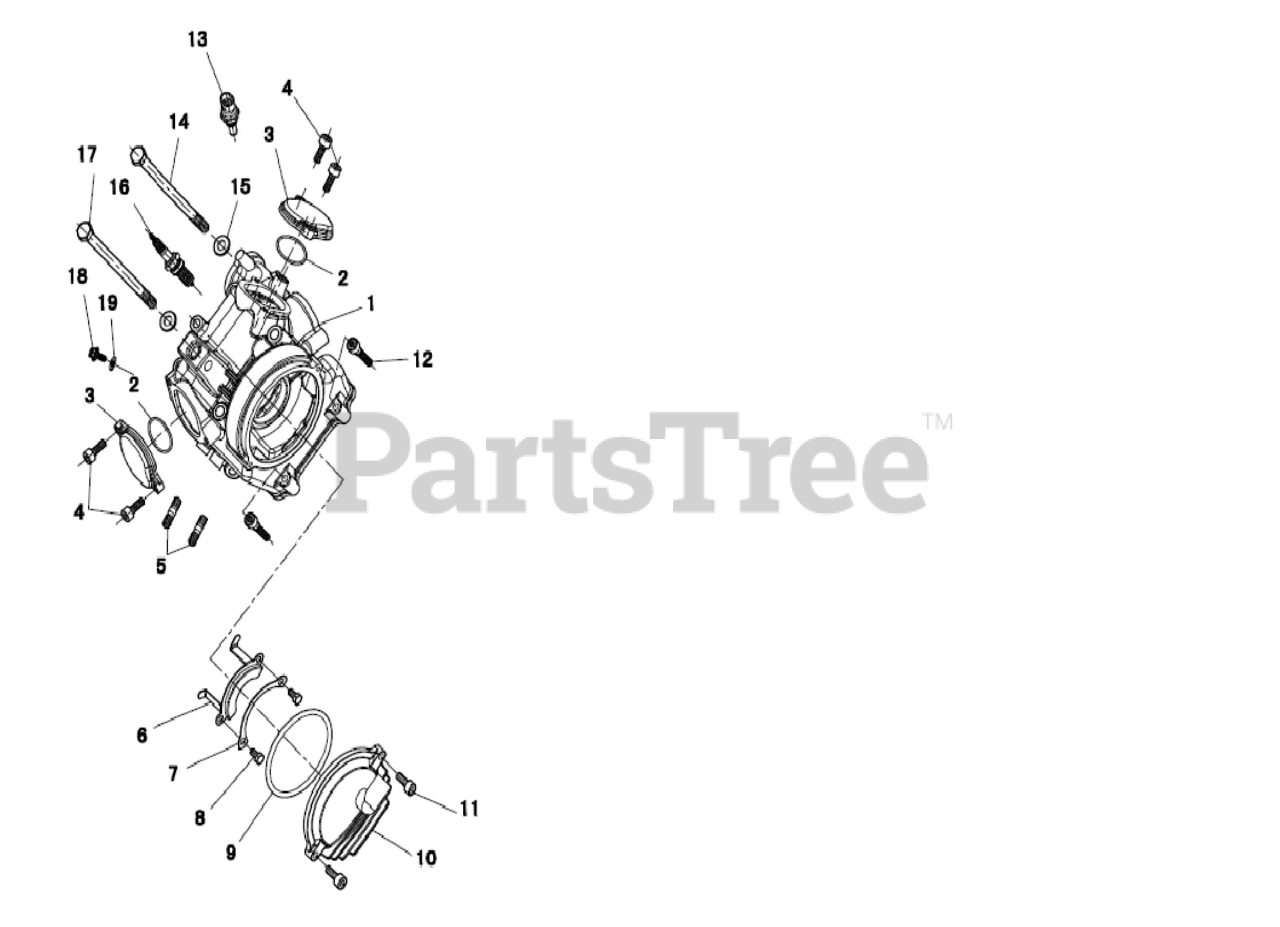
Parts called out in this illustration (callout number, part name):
1	CYLINDER HEAD ASSEMBLY
2	O-RING 58 X 2.4
3	VALVE COVER
4	Hex head cap screw M6X20
5	Stud M8X45(SUS)
6	CAM BEARING HOLDER
7	BOLTS SPACING PLATE
8	BOLTS HEXAGON HEAD M6 X 16
9	O-RING 107 X 2.4
10	CAMSHAFT COVER
11	BOLTS HEXAGON FLANGE M6 X 25
12	Hex head cap screw M8X40
13	Water Temperature Sensor
14	BOLTS CYLINDER M10 X 1.25 X 261
15	Flat Washer 10X 25X3
16	SPARK PLUG
17	BOLTS CYLINDER M10 X 1.25 X 230
18	Hex flange bolts M6X12
19	Aluminum Washer 6X12X1.5
